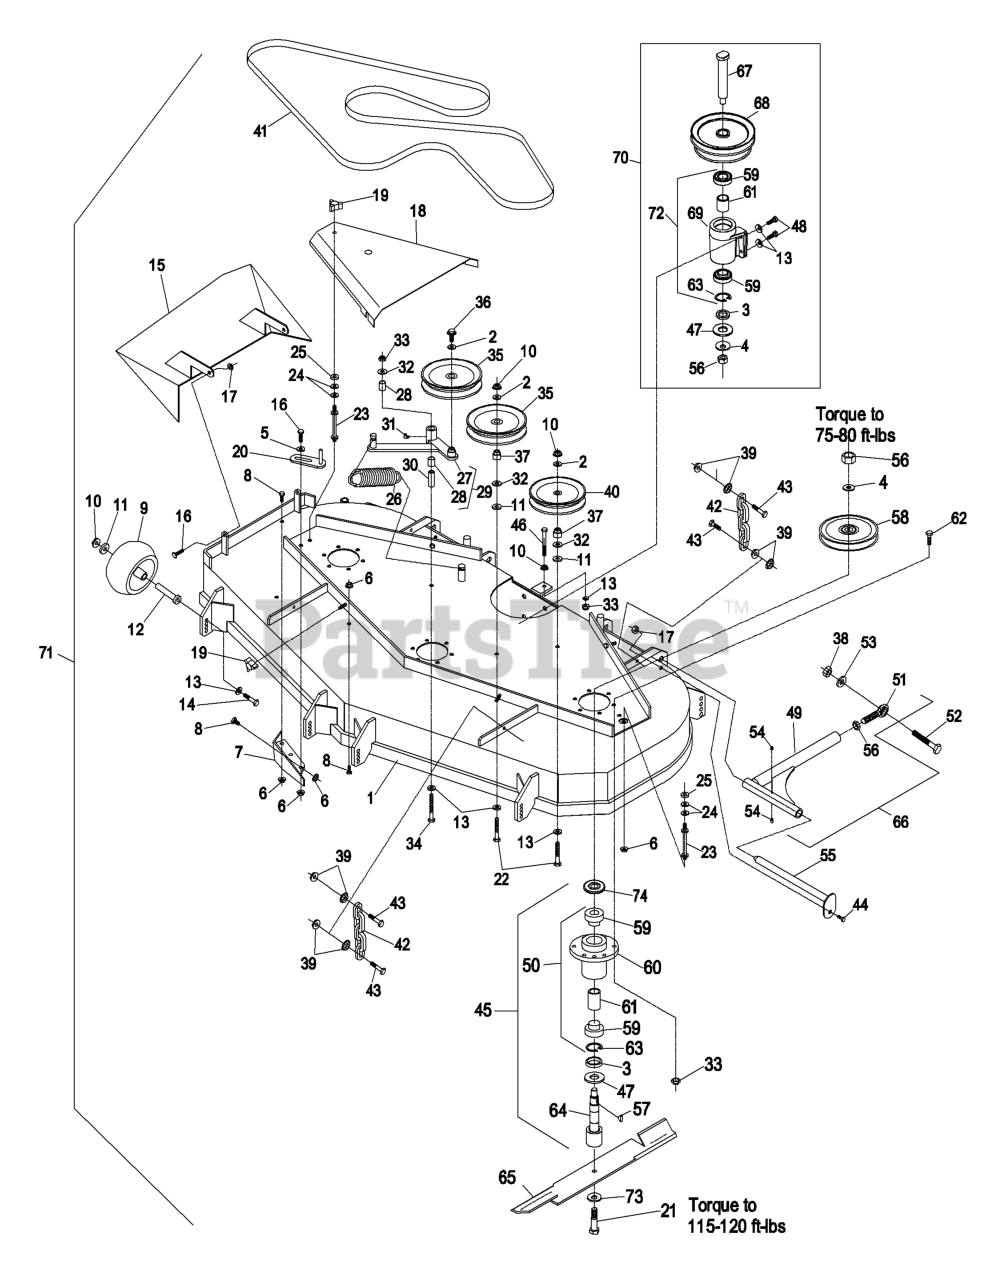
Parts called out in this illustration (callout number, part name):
1	Deck Wldmt, 52"
2	WASHER-FLAT
3	SPACER-PULLEY/BEARING
4	WASHER-SPRING
5	WASHER-SPRING
7	WLD,BAFFLE DISCHARGE
8	SCREW-HH
9	ROLLER-SCALP, ANTI
10	NUT-HHF, WHIZ
12	BUSHING-ROLLER
13	WASHER-BELLEVILLE
14	SCREW-HH
16	SCREW-HH
17	NUT-LOCK, NI
18	SHIELD,BELT 52
19	KNOB-3 PRONG
20	GUIDE-BELT
21	SCREW-CAP
22	SCREW-HH
23	STUD-SHIELD, BELT (SHORT)
24	WASHER-FLAT
28	SLEEVE-BEARING
30	BUSHING
31	FITTING-GREASE, 90 DEG
32	WASHER-FLAT
33	NUT-LOCK, NI
34	SCREW-HH
36	SCREW-HHF
37	BUSHING-IDLER
38	NUT-HEX
40	PULLEY-IDLER
41	BELT,BLADE DRIVE 52
42	CHAIN-LIFT, DECK
43	SCREW-HH
44	SCREW-HH
45	ASM,SPINDLE HSG COMPLETE
46	SCREW-HH
47	GUARD-BEARING, BOTTOM
48	SCREW-HH
51	BALLJOINT-SPHERICAL
52	SCREW-HH
53	WASHER-LOCK
54	FITTING-GREASE
55	PIN-STRUT
56	NUT-HEX
57	KEY-WOODRUFF
58	SHEAVE,BLADE DRIVE
59	BEARING
61	SPACER-BEARING
62	SCREW-HH
63	RING-SNAP
66	STRUT ASM
67	JACKSHAFT
68	SHEAVE,JACKSHAFT-DOUBLE
70	ASM,JCKSHFT KIT 52 3600
71	Complete Deck Asy
73	WASHER-BLADE BOLT, HEAVY
74	GUARD,BEARING TOP .880
